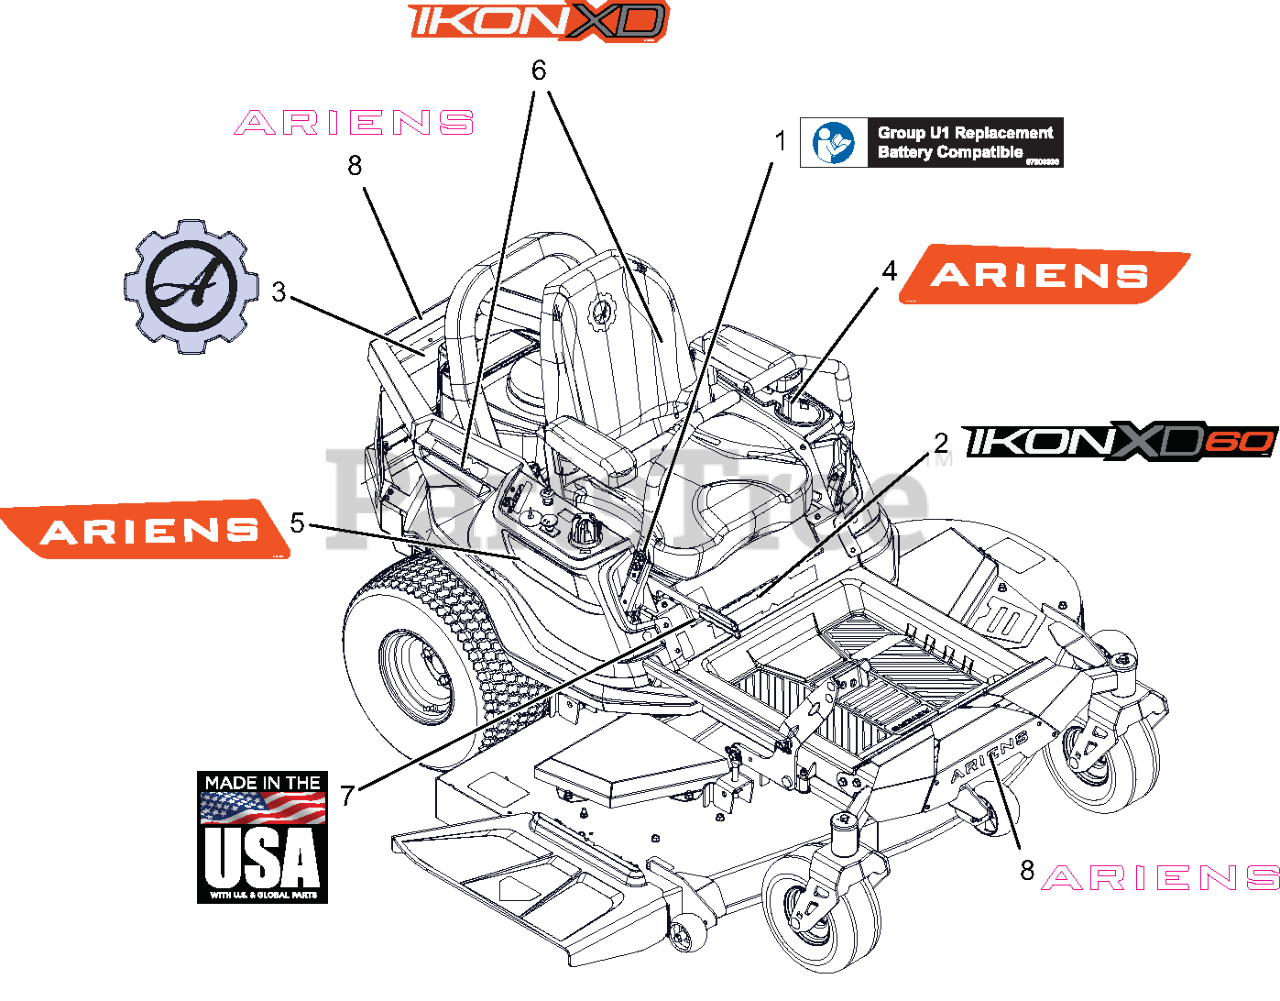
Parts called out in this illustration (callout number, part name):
1	DECAL, U1 BATTERY REPLACEMENT
2	DECAL, IKON-XD 60"
3	DECAL, ARIENS-GEAR BADGE -THK
4	DECAL, FENDER LH
5	DECAL, FENDER RH
6	DECAL, IKON-XD
7	DECAL, MADE IN USA
8	DECAL - ARIENS 9.625"
